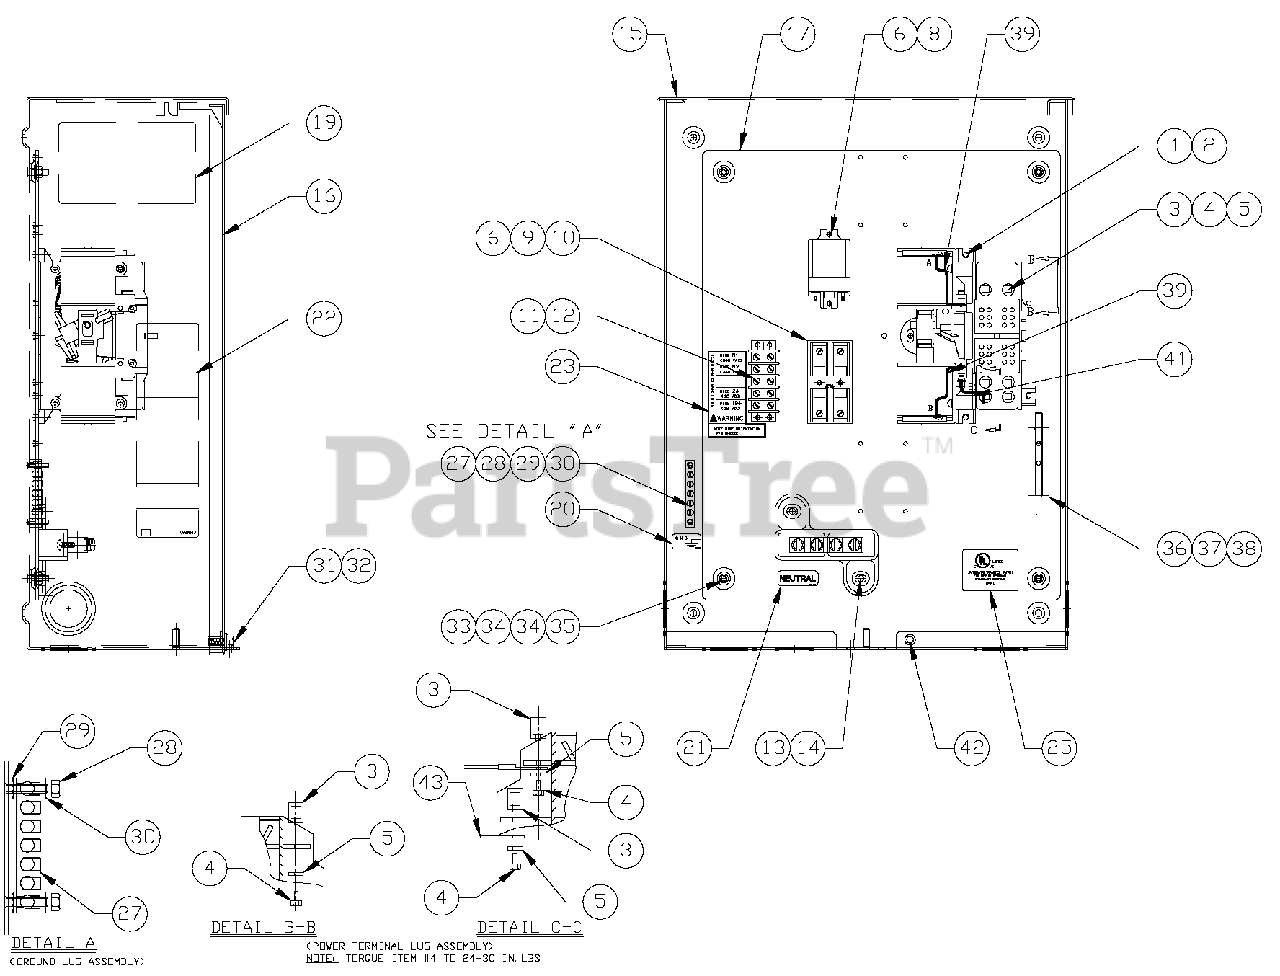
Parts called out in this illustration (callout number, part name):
1	TR SW-HSB 100A 2P 250V
2	SCREW HHTT M5-0.8 X 10 BP
3	LUG SLDLSS 1/0-#14X9/16 AL/CU
4	SCREW, PPHMS 10-32 X 3/8""
5	WASHER, LOCK # 10
6	SCREW HHTT M4-0.7 X 10 BP
8	RELAY PNL 12VDC DPDT
9	FUSEBLOCK 30A 600V 2 POLE
10	FUSE 5A X BUSS HLDR73591
11	BLOCK, TERM 20A 5 X 6
12	RIVET, POP .156 X .67
13	ASS'Y NEUTRAL BLOCK 100A
14	SCREW HHTT M6-1.0 X 12 MM
15	ENCLOSURE, 100/200A TRANSFER SWITCH
16	COVER, TRANSFER SWITCH
17	SUBPLATE, 100/200A XFER SW
19	DECAL, XFER SW NON 100A 120/240
20	DECAL, GROUNDING LUG
21	DECAL, NEUTRAL
22	DECAL, MANUAL 5A FUSE
23	DECAL, TERMINAL STRIP
24	DECAL, TEST SEQUENCE
25	DECAL, UL LIST HSB
26	DECAL, LIVE CIRCUIT ENG/FRN/SPN
27	GROUND BAR (5) 4-14 AWG CONN
28	NUT HEX LOCK M4-0.7 SS NYL INS
29	WASHER SHAKEPROOF EXT #8 STEEL
30	WASHER FLAT M4
31	SCREW HHC 1/4-20 X 1/2 SS
32	WASHER M6 NYLON INT HEX
33	NUT HEX 1/4-20 SS
34	WASHER FLAT 1/4-M6 ZINC
35	WASHER LOCK M6-1/4
36	BRACKET, ARM EXTENDER
37	ARM EXTENDER PIN
38	RIVET POP .156 X .362 AL
41	WIRE-E1
42	NUT TRIC 1/4-20 X .525
